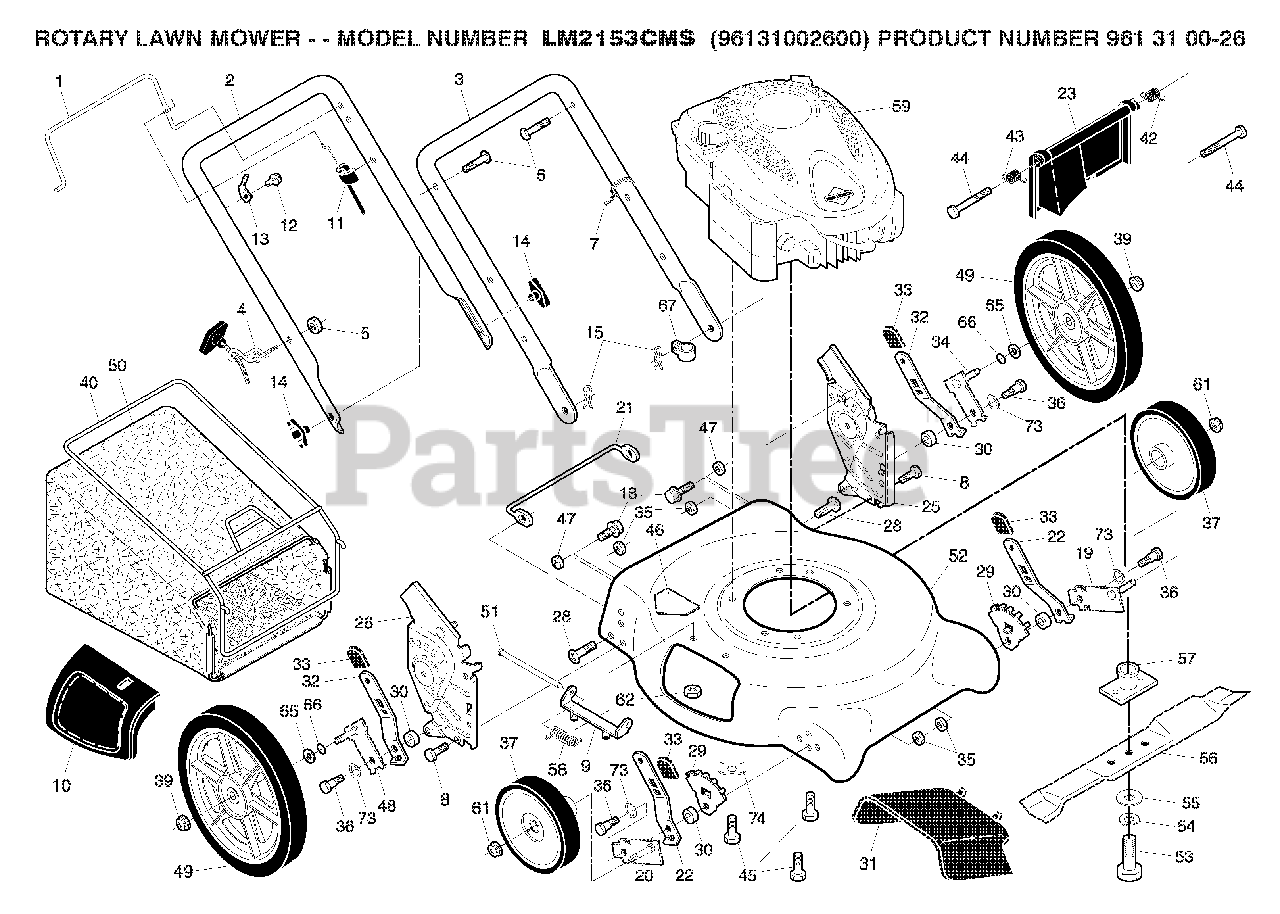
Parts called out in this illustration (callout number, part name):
2	HANDLE.UPPER
3	HANDLE.LOWER.BLACK
4	GUIDE.ROPE.STD.BLK.ZIN
5	NUT
6	BOLT, HANDLE 5/16-18X1.75
7	TIE GUIDE
8	BOLT
9	HINGE BRACKET
10	MULCH DOOR
11	CABLE.ENGINE.ZONE.CONTROL
14	KNOB, DEFLECTOR
15	HAIRPIN COTTER
19	AXLE ARM ASSY FRONT LH
20	AXLE ARM ASSY FRONT RH
22	SELECTOR SPRING, FRONT
23	REAR DOOR ASSY
25	BRACKET.ASM.HAND.HW.21.LT
29	WHEEL ADJ BRACKET FRONT
30	SPACER.HEIGHT.ADJUSTER
31	CLIP ON DISCHARGE GUARD
32	SPRING.SEL.EXT.21.DOMED.12/14
33	SELECTOR KNOB
34	AXLE ARM ASSY REAR LH
35	LOCKNUT 5/16-18
36	SHOULDER BOLT 5/16-18
39	NUT.HEX.FLANGE.3/8-16.LOCKNUT
40	FRAME.BAG.21.REAR.DOMED.PUSH
42	SPRING.LH.22.REAR.DOOR.EZ.EMPT
43	SPRING.RH.22.REAR.DOOR.EZ.
45	BOLT 3/8-16X1-1/8
46	DECAL.INTERNATIONL.CUTFINGER
48	AXLE ARM ASSY REAR RH
50	GBAG.
51	ROD.HINGE.COMBI-C
53	SCREW, HEX HD 3/8-24 X 1-3/8
54	LOCKWASHER
55	WASHER,HARDEN
56	BLADE.21.PUSH
57	ADAPTER.BLADE
58	TORSION SPRING
61	NUT.HEX.FLANGE.3/8-16.LOCKNUT
62	LOCKNUT
65	WASHER PM
66	O-RING..070X.487.NEOPRENE
67	CLIP.CABLE.BLK
73	WASHER FLAT
